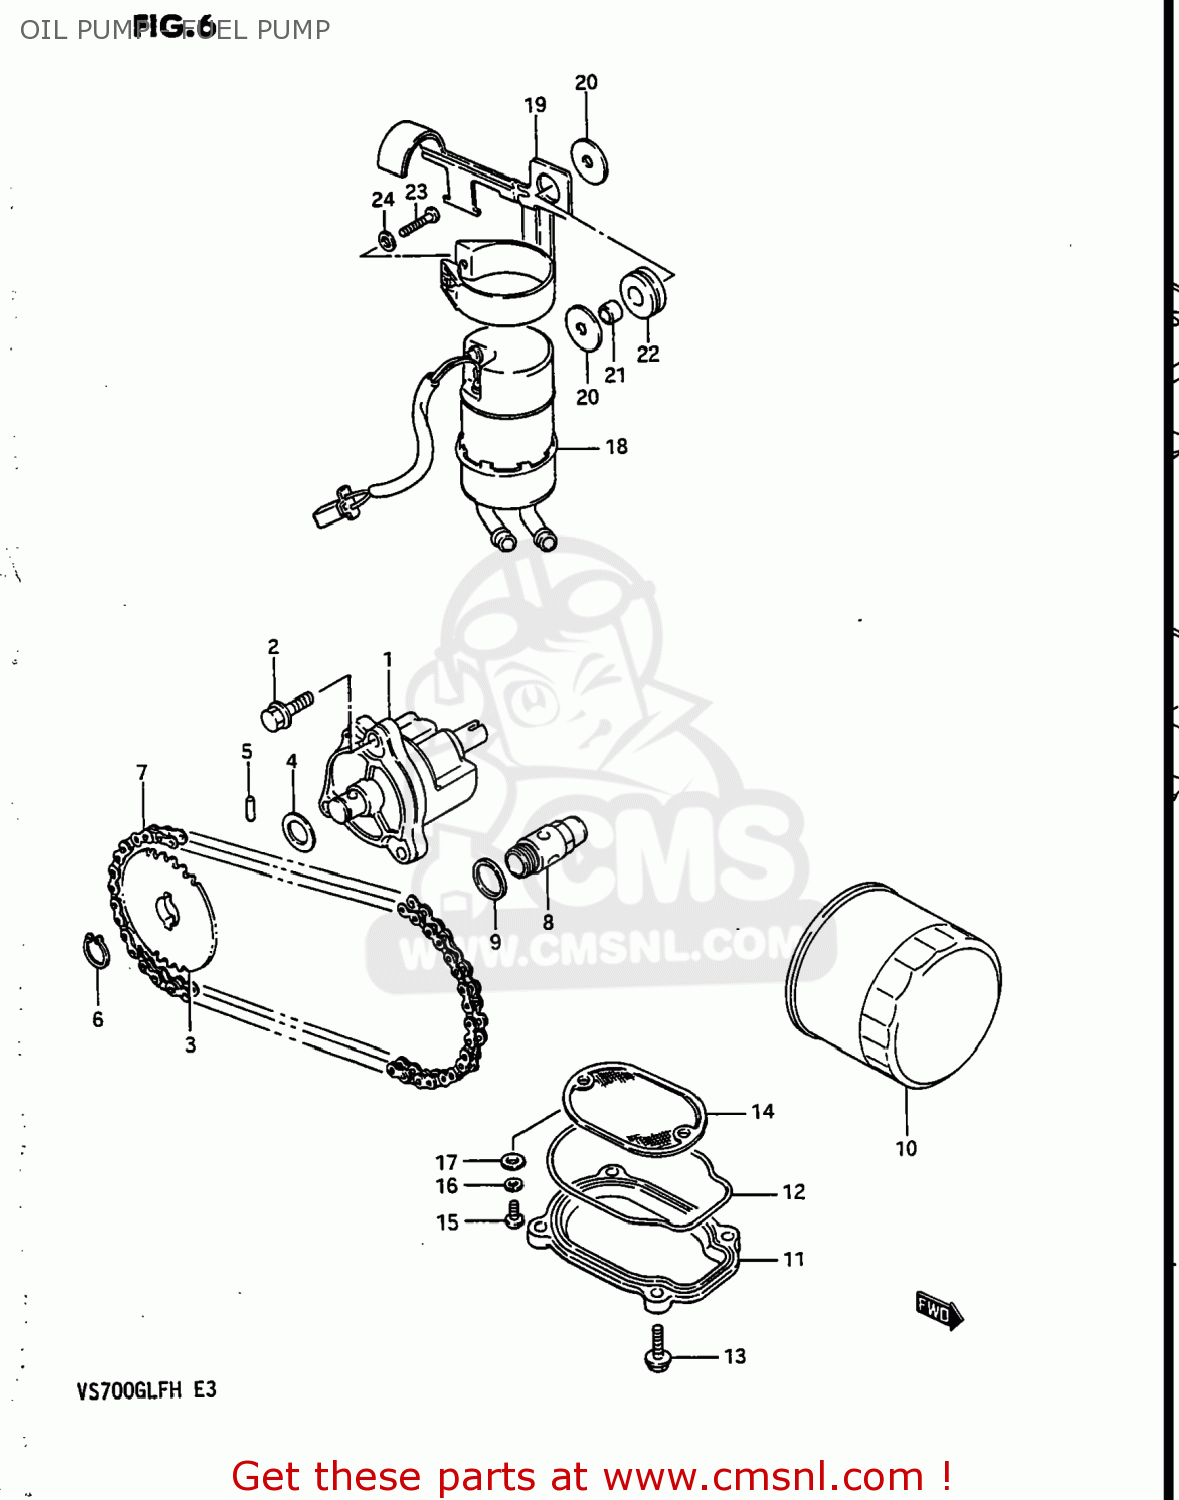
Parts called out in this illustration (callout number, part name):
1	PUMP ASSEMBLY,OIL
2	BOLT
3	SPROCKET,OIL PUMP DRIVEN
4	SHIM
5	PIN(5X18)
6	CIRCLIP
7	CHAIN,OIL PUMP DRIVE
8	VALVE ASSY,OIL RELIEF
9	GASKET(16X22X2) (NAS)
10	FILTER,OIL
11	CAP,OIL STRAINER
12	O RING,OIL STRAINER CAP
13	BOLT,REAR
14	STRAINER,ENGINE OIL
15	SCREW 5X12
16	LOCK WASHER
17	WASHER
18	PUMP ASSY,FUEL
19	BRACKET,FUEL PUMP
20	WASHER (6.5X24X1.6)
21	SPACER(6.5X10.5X6.5)
22	CUSHION
23	SCREW
24	WASHER
